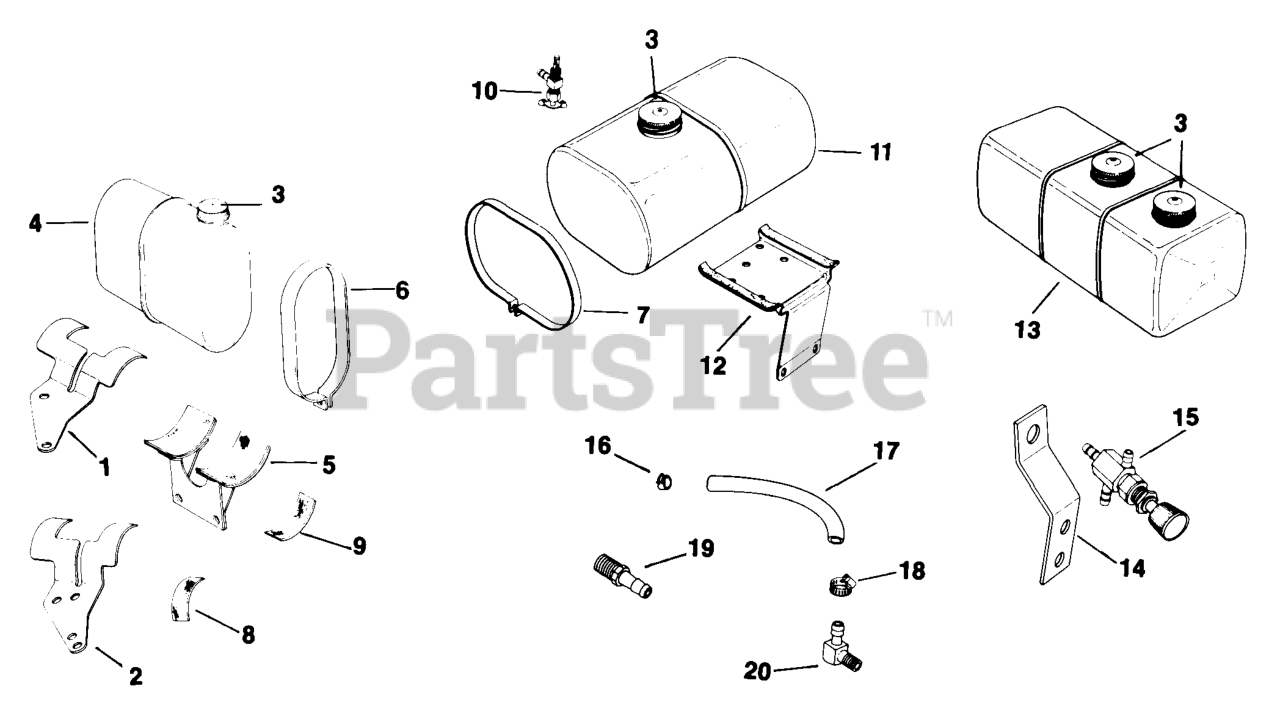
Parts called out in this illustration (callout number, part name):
7	STRAP
11	TANK, FUEL USE 47 065 13-S
12	BRACKET
